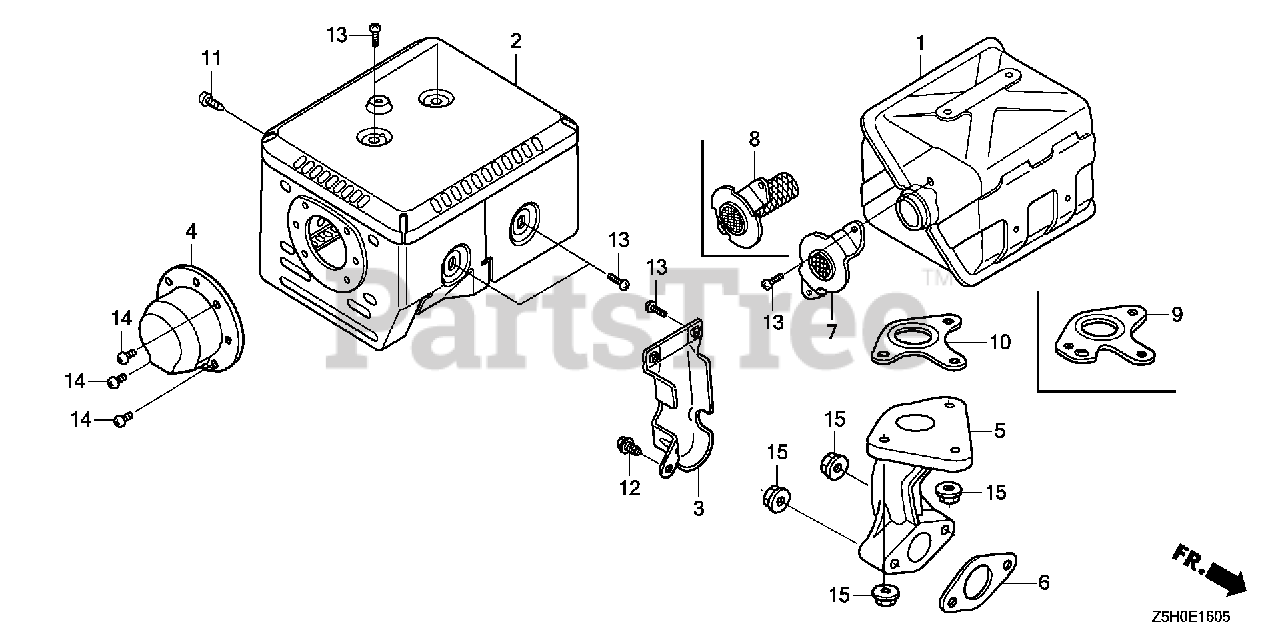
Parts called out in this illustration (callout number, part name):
1	MUFFLER
2	PROTECTOR, MUFFLER
3	PROTECTOR, EX. PIPE
6	GASKET, EX. PIPE
7	FLANGE, BAFFLE
8	ARRESTER, SPARK
9	GASKET, MUFFLER (ARRESTER) (NIPPON LEAKLESS)
10	GASKET, MUFFLER (NIPPON LEAKLESS)
11	SCREW, TAPPING (6X10)
12	BOLT, FLANGE (6X12) (CT200)
13	SCREW, TAPPING (5X8)
15	NUT, FLANGE (8MM)
